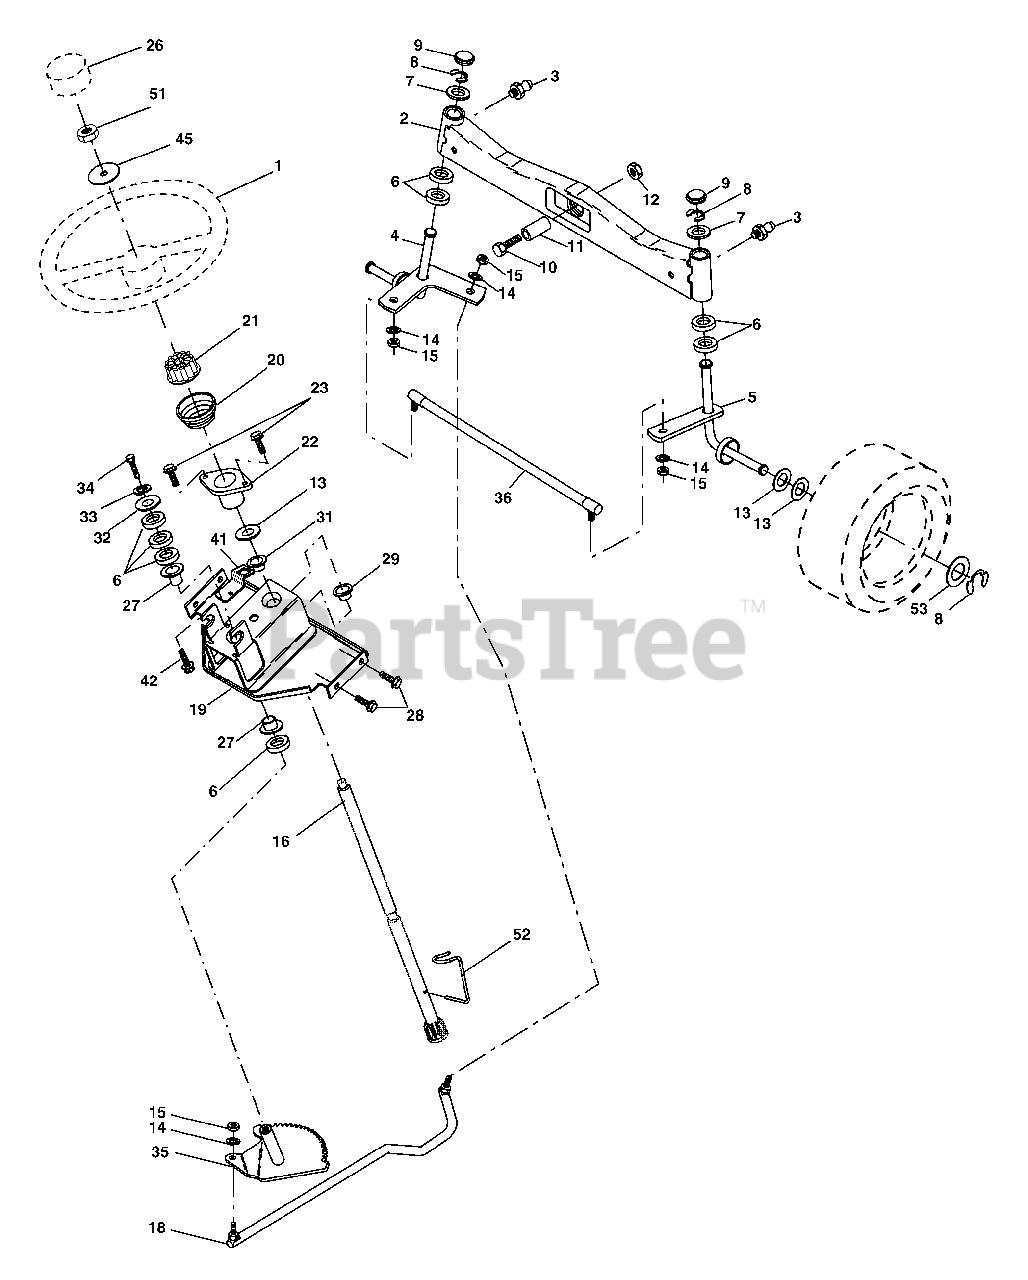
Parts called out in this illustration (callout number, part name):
1	Wheel, Steering
2	Axle Asm., Front
3	Fitting, Grease
4	Spindle Asm, LH
5	Spindle Asm., RH
6	Bearing, Race Thrust Harden
7	Washer 25/32 x 1-5/8 x 16 Ga.
8	Ring Klip #T5304-75
9	Cap, Spindle
10	Bolt, Fin Hex 5/8-11 x 2-3/4
11	Spacer Bearing Axle Front
12	Nut, Lock Flange 5/8-11 Unc
13	Washer 25/32 x 1-1/4 x 16 Ga.
14	Washer, Lock Hvy Hlcl Spr 3/8
15	Nut, Crownlock 3/8-24
16	Shaft Asm., Steering
18	Draglink, Ball Joint Solid Vgt
19	Support Asm., Steering Vgt
20	Boot, Steering
21	Adapter, Wheel Steering
22	Bushing, Strg. Blk
23	Screw
26	Cap, Wheel Steering
27	Bearing, Col. Strg.
28	Screw 3/8-16 x 3/4
29	Bearing, Flange
31	Bushing, Nyliner Snap
32	Washer 11/32 x 1 x 10 Ga.
33	Washer, Lock Hvy Hlcl Spr 5/16
34	Bolt, Fin Hex Hd 5/16-18 x 3/4
35	Gear, Sector Steering
36	Tie Rod
41	Bracket Switch Interlock VGT 97
42	Screw Thdrol 5/16-18 x 1/2 Tyt
45	Washer 9/16 ID x 2-3/8 OD 12 G zin
51	Nut Hex Jam Toplock 1/2-20 unf
52	Clip Steering
53	Washer Hardened
